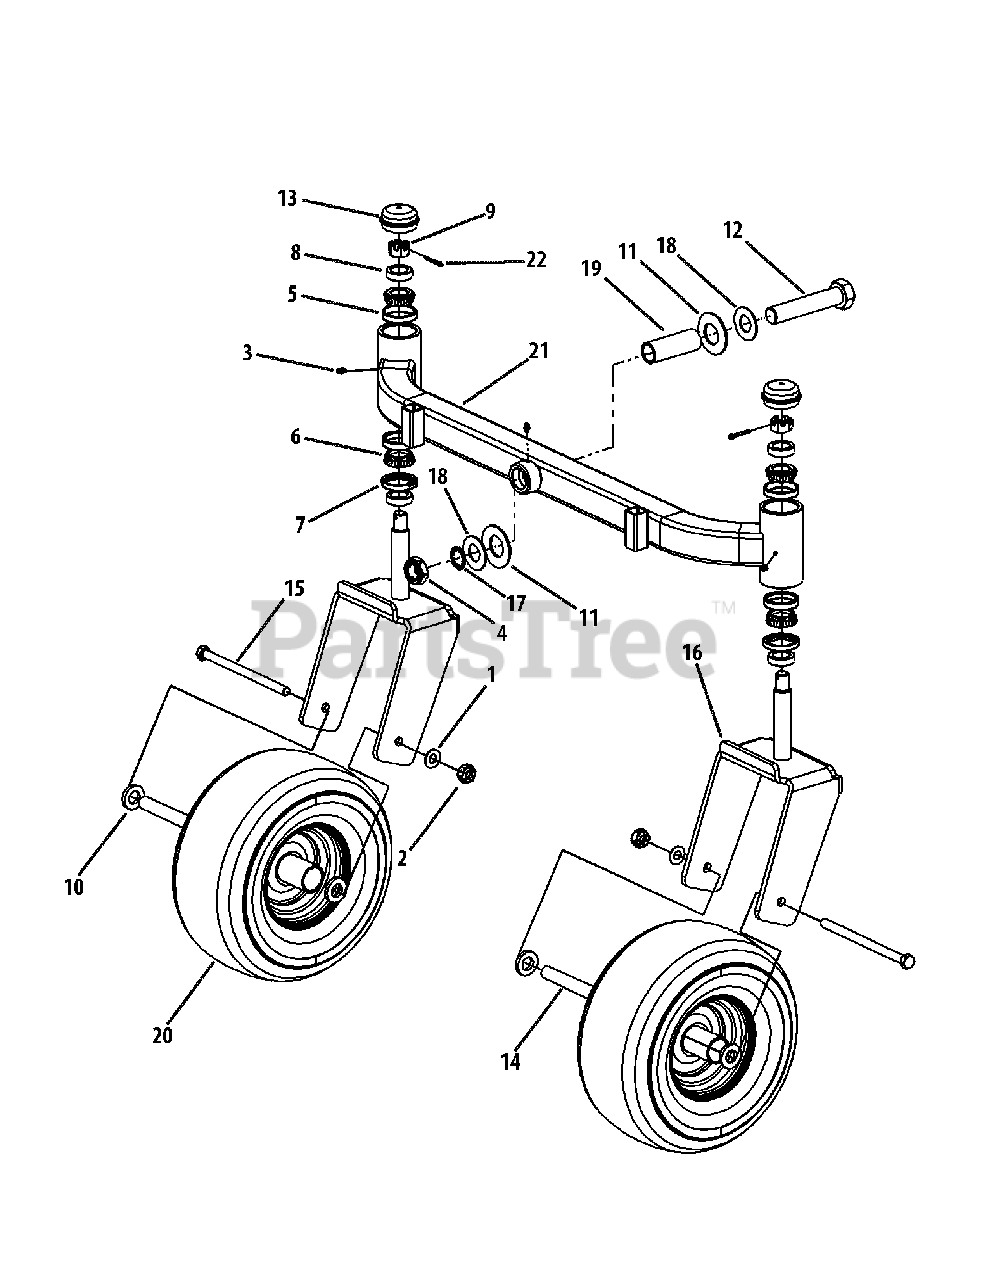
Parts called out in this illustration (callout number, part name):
1	Washer, 1/2 x 1 Shim
2	Nut, 1/2-20, Center Lock
3	Grease Fitting, 1/4-28 x 3/16
4	Nut, Jam, 1.0-14, Insert Lock
5	Cup Bearing
6	Bearing Cone
7	Seal
8	Ring Seal
9	Slotted Nut, 3/4-16
10	Spacer, .812 ID x .218LG
11	Bell Washer, 1.25 ID x 2.5 x .157
12	Hex Cap Screw, 1-14 x 5.0
13	Grease Cap, 1.986 OD
14	Wheel Spacer
15	HHCS, 1/2-20, 7.50
16	Yoke, Caster Wheel
17	Retainer Extension, Self Locking
18	Flat Washer, 1.00 ID
19	Spacer, 1.005 ID x 1.25 OD x 3.6
20	Wheel, 13 x 6.50 x 6.0, Beige
20	Roller Bearings (per tire)
20	Retainer Bushings (per tire)
21	Front Axle Assembly 48"
21	Front Axle Assembly 60"
22	Cotter Pin, 5/32, 1.25
